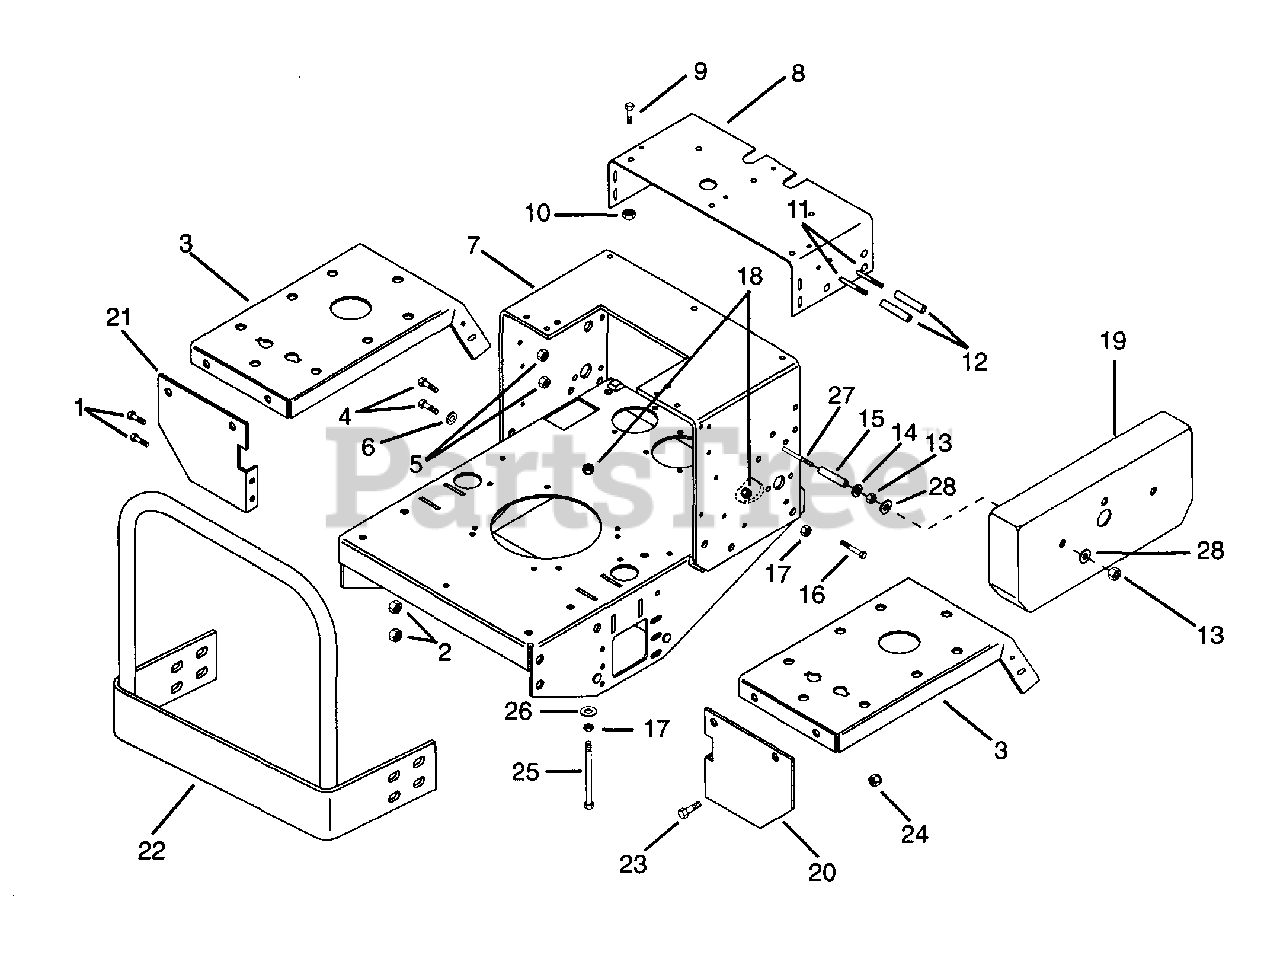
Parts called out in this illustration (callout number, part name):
1	Bolt-Hex .38-16 x 1.25 Grade 5
2	Nut-Locking-Nylon .375-16 Grade 2
4	Bolt-Hex .25-20 x .75 Grade 5
5	Nut-Locking-Nylon .250-20 Grade 2
6	Washer-Flat-Steel .281 x .625 x .065
7	Weldment, Frame Z
8	Support Control Weldment
9	Bolt-Hex .375-16 x 1.00 Grade 5
10	Nut-Locking-Nylon .375-16 Grade 2
11	Bolt-Hex .31-18 x 4.00 Grade 5
12	Spacer, Split-Rolled
13	Nut-Locking-Nylon .312-18 Grade 2
14	Washer-Flat-Steel .344 x .688 x .065
15	Spacer, Split-Rolled
16	Bolt-Hex .38-16 x 3.00
17	Nut-Hex .375-16 Grade 2
18	Nut-Locking-Nylon .375-16 Grade 2
19	Guard, Linkage
20	Support, Fender Right Hand
21	Support, Fender Left Hand
22	Weldment, Rear Guard
23	Bolt-Hex .31-18 x .75 Grade 5
24	Nut-Locking-Nylon .312-18 Grade 2
25	Bolt-Hex .38-16 x 4.00
26	Washer-Flat-Steel .406 x .812 x .065
27	Bolt-Hex .31-18 x 3.75 Grade 2
28	Washer-Flat-Steel .313 x .875 x .065
